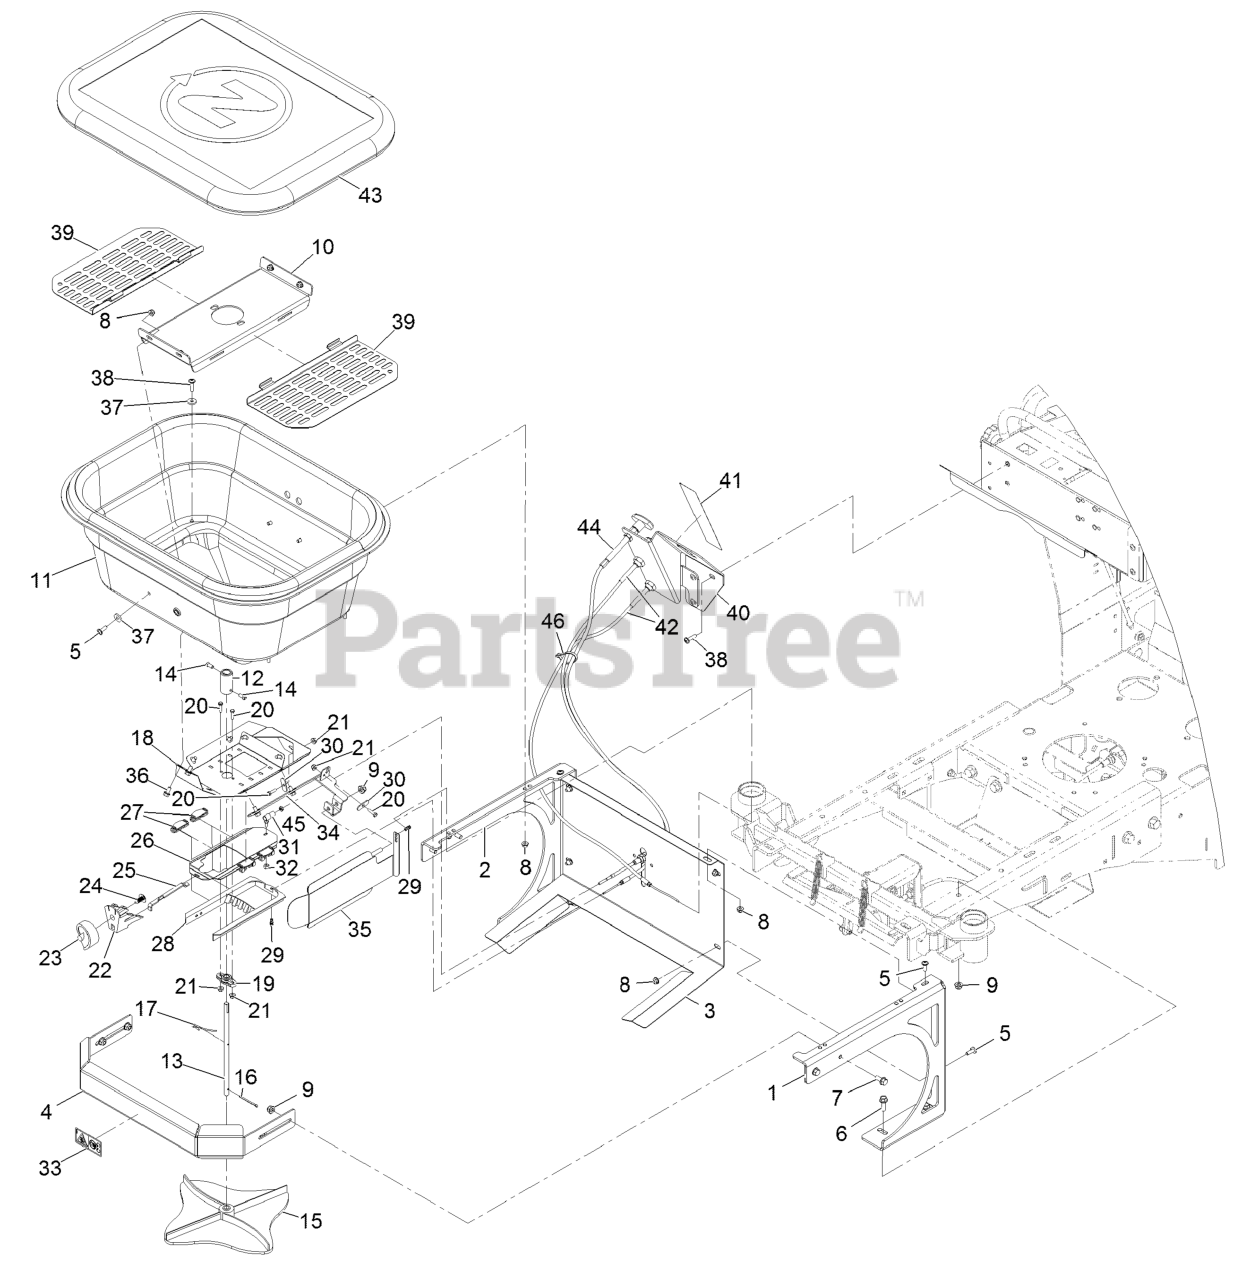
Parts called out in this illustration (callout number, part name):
1	WLD, FRAME, HOPPER, L, 120
2	WLD, FRAME, HOPPER, R, 120
3	BACKSHIELD, HOPPER, JR36
4	BUMPER, FRONT, HOPPER, 120
5	Screw-Hsbhf
6	SCREW-HHF
7	SCREW-HHF
8	Nut-Hex Flange
9	Nut-Hex Flange
10	PAN, HOPPER, 120
11	120 LBS HOPPER\N05-296-22
12	COUPLER-SS
13	SHAFT, HOPPER, 120
14	Screw-SQH
15	SPINNER-SPREADER
16	PIN-COTTER
17	WIRE-AGITATOR
18	BASE PLATE, HOPPER, 120
19	BEARING-FLANGE
20	SCREW-HH
21	Nut-Hex Flange
22	MOUNT-DIAL
23	DIAL
24	CLIP
25	LINKAGE-GATE, RATE
26	Slide-Door, Hopper
27	GUIDE-RATE, GATE
28	DIFFUSER
29	RETAINER-CABLE, WIRE
30	RETAINER, CABLE
31	BALL JOINT-SS
32	Nut,NYL Lock,#10-32,ST/ST 18-8
33	Decal-Dismemberment Hazard
34	Mount-Deflector, Side
35	Deflector-Side, Spreader
36	SCREW-HHF
38	Screw-Hsbhf
39	SCREEN, HOPPER, 120
40	MOUNT-SPEEDOMETER
41	Decal-Hopper Control
42	CABLE-PUSH/PULL
43	COVER-HOPPER, SMALL
44	120LB HOPPER CABLE
45	Nut,Hex Jam Mch Scr,10-32,Sst
46	TIE-CABLE
